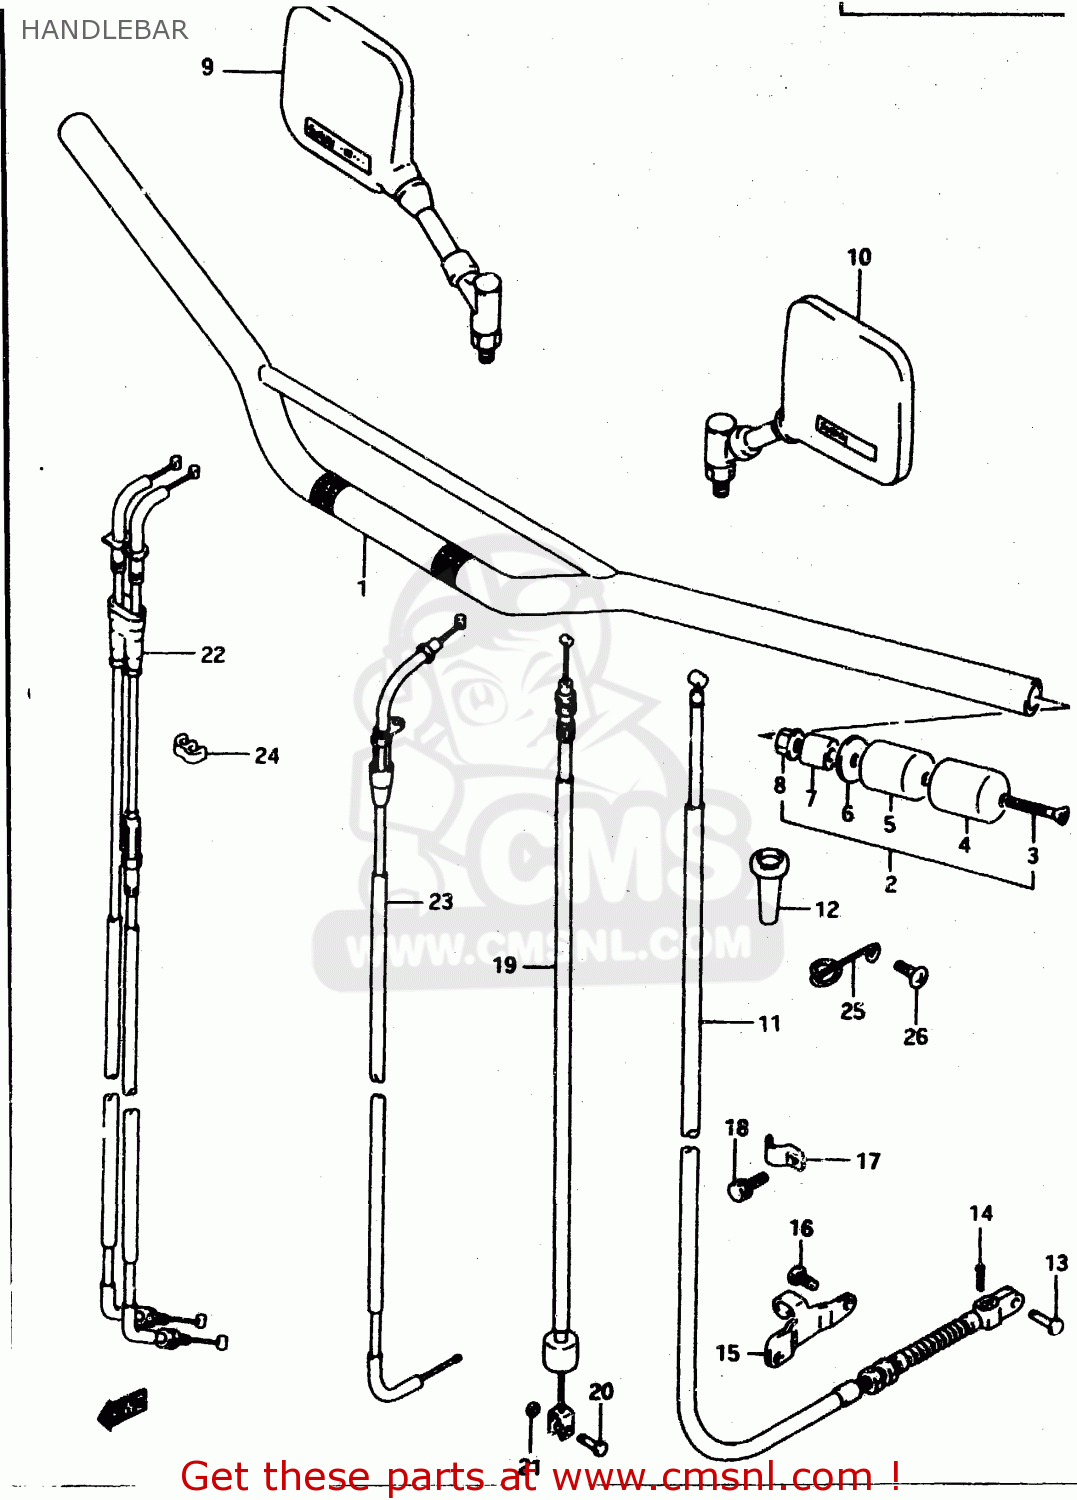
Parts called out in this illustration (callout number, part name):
1	HANDLEBAR
2	BALANCER SET,HANDLEBAR
3	SCREW
4	CAP,BALANCER
5	BALANCER,HANDLE
6	SPACER,BALANCER
7	EXPANDER,HANDLE BALANCER
8	NUT
9	MIRROR ASSY,RR VIEW,R
10	MIRROR ASSY,RE
11	CABLE ASSY,CLUTCH
12	BOOT,CLUTCH CABLE
13	PIN(L:13)
14	PIN
15	STOPPER,CLUTCH CABLE
16	BOLT
17	CLAMP
18	BOLT
19	CABLE ASSY,DECOMP
20	PIN(4X12.5)
21	E RING
22	CABLE ASSY,THROTTLE
23	CABLE,STARTER
24	CLIP
25	GUIDE,CLUTCH CABLE
26	SCREW
